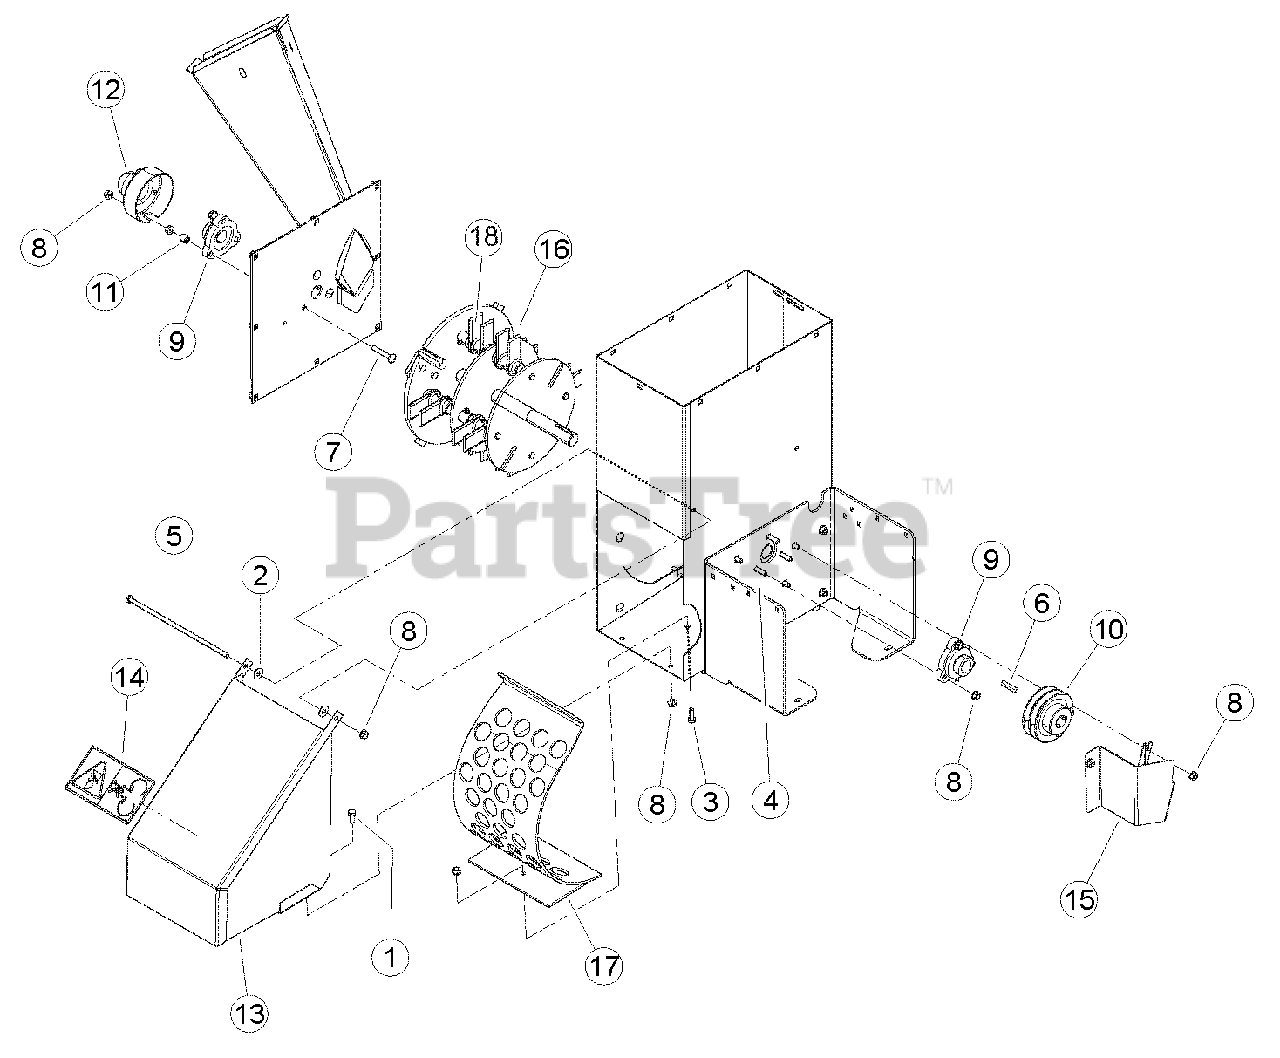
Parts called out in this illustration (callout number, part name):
1	BOLT, 5/16 X 3/4 HEX HD GR5 ZP
2	WASHER, 5/16 FLAT ZP
3	BOLT, 5/16 X 7/8 HEX HD NC GR5 ZP
4	BOLT, 5/16 X 1-1/4 CRG GR5 ZP
5	BOLT, 5/16 X 10 HEX HD GR5 NC ZP
6	KEY, 1/4 SQUARE X 1-1/2 LONG PLAIN
7	BOLT, 5/16 X 2 CRG GR5 NC ZP
8	NUT, 5/16 FLANGE TOPLOCK
9	BEARING, 1" FLUSHMOUNT CAST W/COLLAR
10	PULLEY, 4X1 2A GROOVE
10	PULLEY, CAST 4" OD,1"BORE,B GRV (SC3206 ONLY)
11	SPACER .54 OD X .50 LG
12	CAP, ROTOR SHAFT END CAP
13	ASSY, WIDE CE COMPLIANT DISCHARGE, SERVICE PART
13	ASSY, NAR. CE COMPLIANT DISCHARGE, SERVICE PART - SC3206 ONLY
14	DECAL, BLADE DANGER ISO
15	SHIELD, LOWER
16	ASSEMBLY, BALANCED ROTOR (REPLACED AND SUPERSEDED. FOR SERVICE OF ROTOR ASSEMBLY ORDER KIT #74209-00, ASSEMBLY WITH KNIVES)
16	ASSY, NARROW ROTOR W/ CAST FLAILS (SC3206 ONLY) (REPLACED AND SUPERSEDED. FOR SERVICE OF ROTOR ASSEMBLY ORDER KIT #77591-00, ASSEMBLY WITH KNIVES)
17	WELDMENT, WIDE COARSE TAPERED
17	WELDMENT, NAR. COARSE TAPERED (SC3206 ONLY)
18	SHREDDER FLAIL (REPLACED AND SUPERSEDED. FOR SERVICE ORDER KIT #70973, SHREDDER KNIVES KIT)
18	SHREDDER FLAIL (SC3206 ONLY) (REPLACED AND SUPERSEDED. FOR SERVICE ORDER KIT #77589-00, SHREDDER KNIVES KIT)
